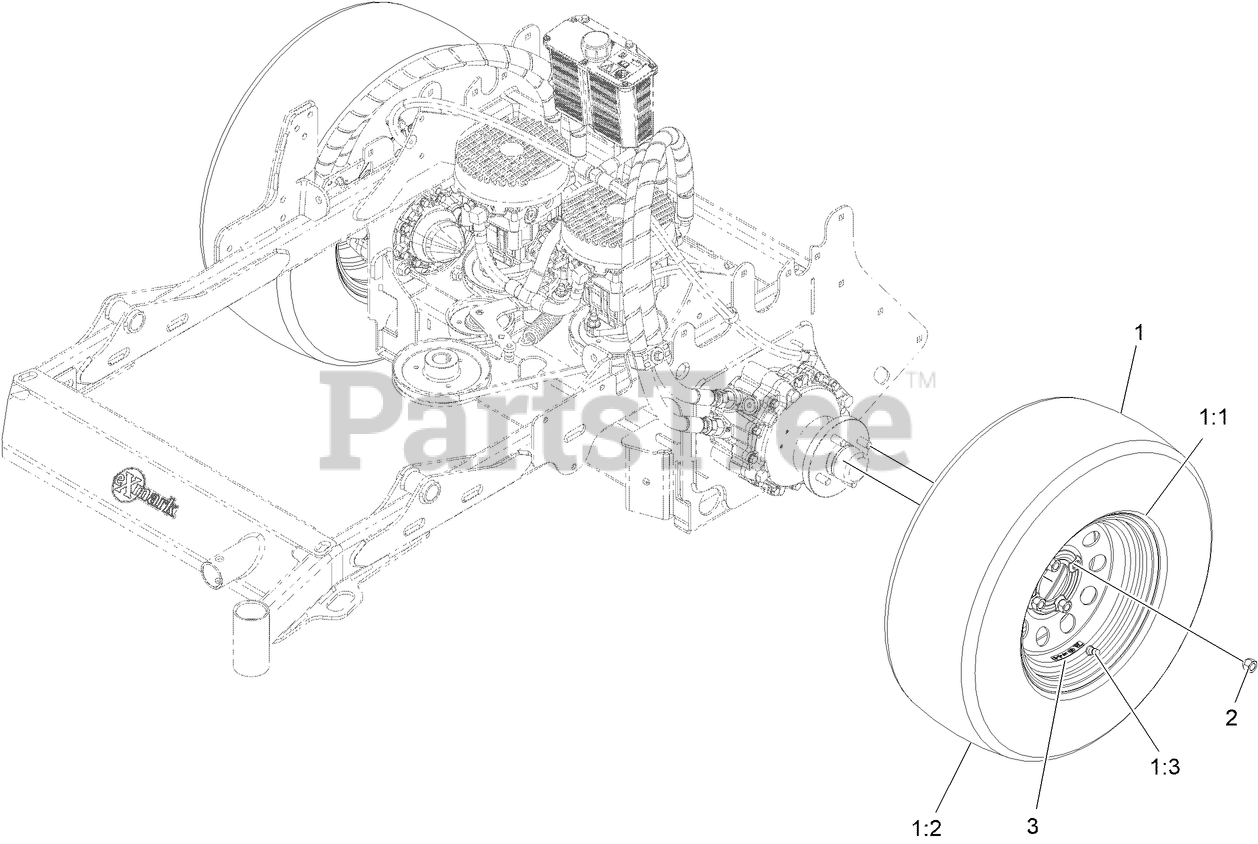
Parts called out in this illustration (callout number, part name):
1	ASM-WHL/TIRE 24X9-12
1:1	WHEEL-WHITE 12X7.0
1:2	TIRE-24X9.00-12
1:3	VALVE
2	NUT-LUG
3	DECAL-TORQUE,WHEEL
